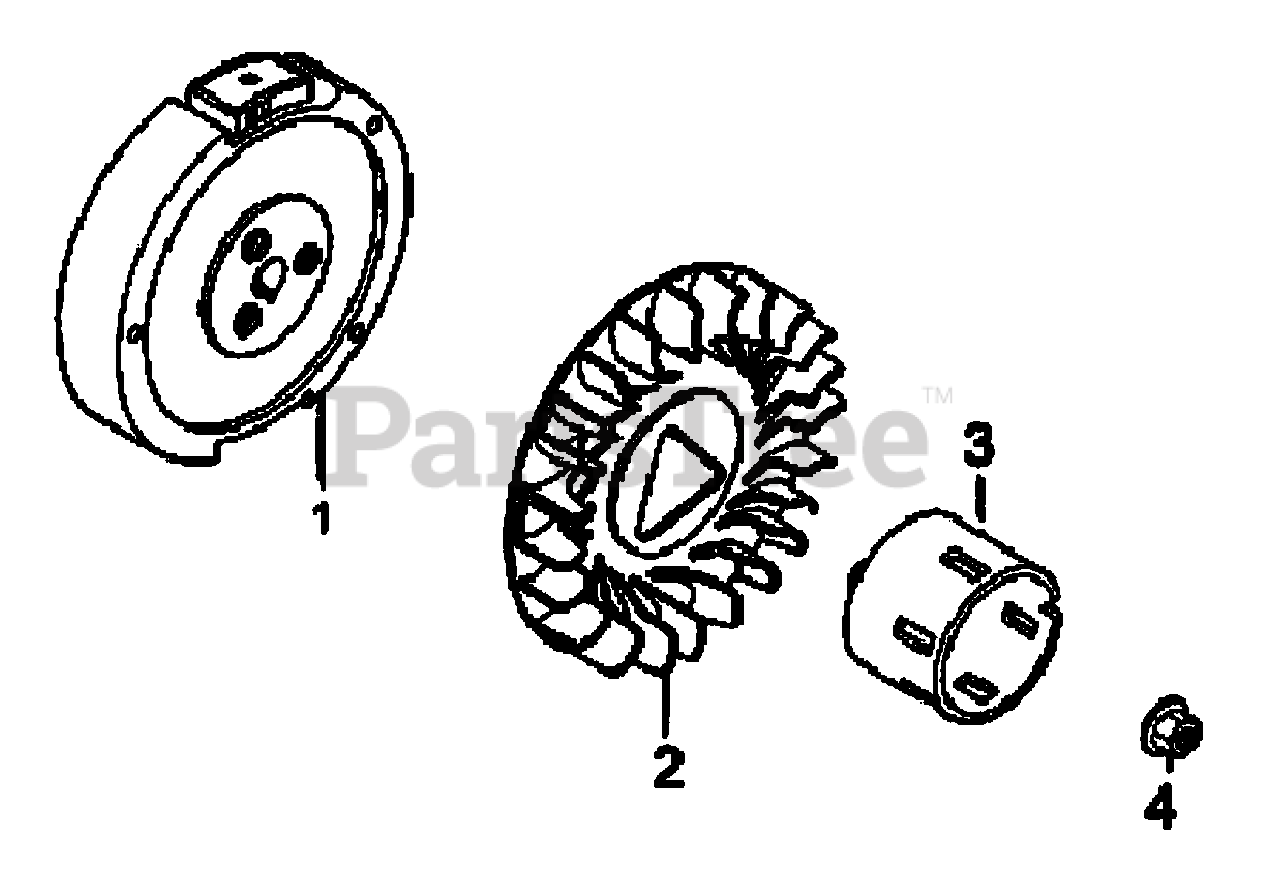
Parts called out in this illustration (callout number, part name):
2	FAN, COOLING
3	PULLEY, STARTER
4	NUT, SPECIAL, M16
